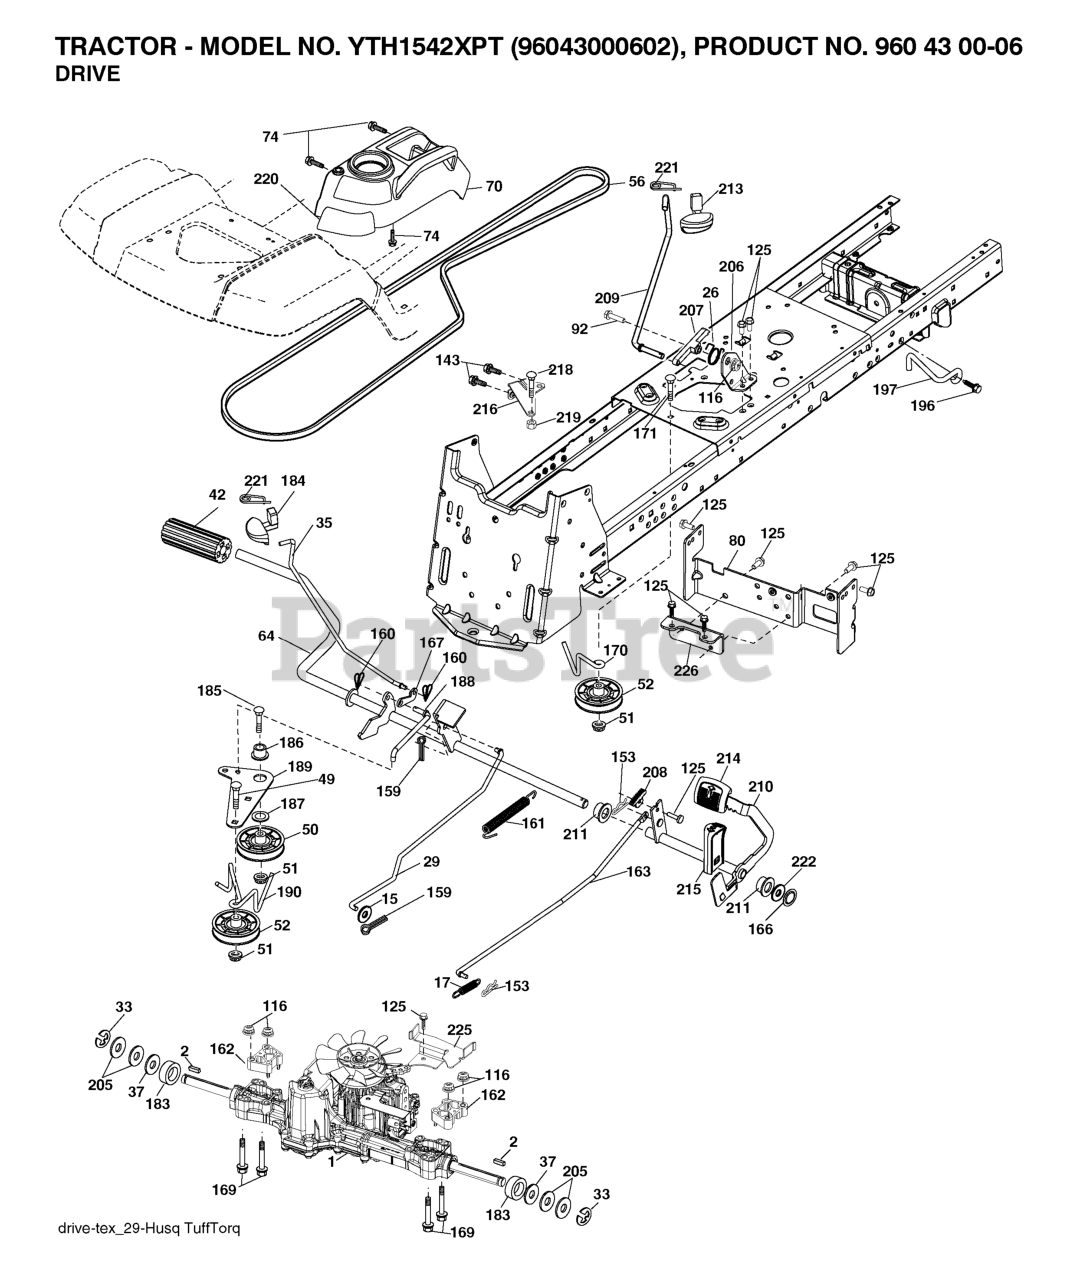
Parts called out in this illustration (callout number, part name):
1	TRANSAXLE, TUFFTORQ K46
2	SQUARE KEY
15	WASHER
17	SPRING.BRAKE.K46
26	SPRING.RETURN.CRUISE
29	ROD.BRAKE.K46
35	ROD.BRAKE.PARKING.GT.H
42	PEDAL COVER T
50	IDLER.FLAT.910.OFFSET
51	NUT LOCK FLG 3/8-16 UNC
52	IDLER.V-GROOVE.910.OFFSET
56	V-BELT.MOWER.92.40.42/K46
64	SHAFT.ASM.PEDAL.BRK.CNTR
70	RP CONSOLE.ASM.PCH.W/TB
74	SCREW.HI-LO.CONSOLE
80	STRAP.TORQUE.HG3000/K46
92	BOLT
116	NUT LOCK HEX FLANGE 5/16-18
125	SCREW
143	Screw 5/16-18 x 1/2 Hex, Self Tapping 5/16-18 x 1/2
153	RETAINER M
159	COTTER PIN
160	RETAINER CLIP
161	SPRING.RETURN.CLUTCH.2006
162	SPACER.TRANSAXLE.18&22
163	ROD.CONTROL.PEDAL.K46
166	NUT.PUSH.625.2006
167	LATCH.BRAKE.SPRING
169	BOLT.HEX.FLNG.5/16-18X3.75
170	KEEPER.V-IDLER.CENTER.
183	SPACER AXLE
184	HANDLE.PARKG.BRK.HUSQ X667
186	SPACER.RETAINER
187	WASHER 12/32X2X10GA
188	RP.LINK.CLUTCH.GROUND.DRIVE
189	BELLCRANK.GROUND.DRIVE.TEX.
190	KEEPER.BELLCRANK.DRIVE
196	SCREW 3/8-16X1
197	LINK.CLUTCH.ANIT-ROTAT
206	BRKT.MOUNT.LATCH.CRUIS
207	LATCH.CONTROL.CRUISE
208	GEAR.SECTOR.CONTROL.CR
209	ROD.CONTROL.CRUISE.GT.
210	ROCKER.ASM.PEDAL.CONTR
211	BEARING.NYLON
213	KNOB.CONTROL.CRUSIE.HU
214	PEDAL.FORWARD.TEX.GT.4
215	PEDAL.REVERSE.TEX.GT.4
216	BRACKET.PULLEY.IDLER.W/TEX
218	BOLT.5/16-18X1-1/4 FULL.THREAD
219	SPACER.FENDER
220	REFLECTOR.RH.TEX GT
221	RETAINER.SPRING.CLIP.H
222	WASHER
225	KEEPER.BELT.TRANSAXLE.K46
226	BRKT.MOUNT.TORQUE.K46.
